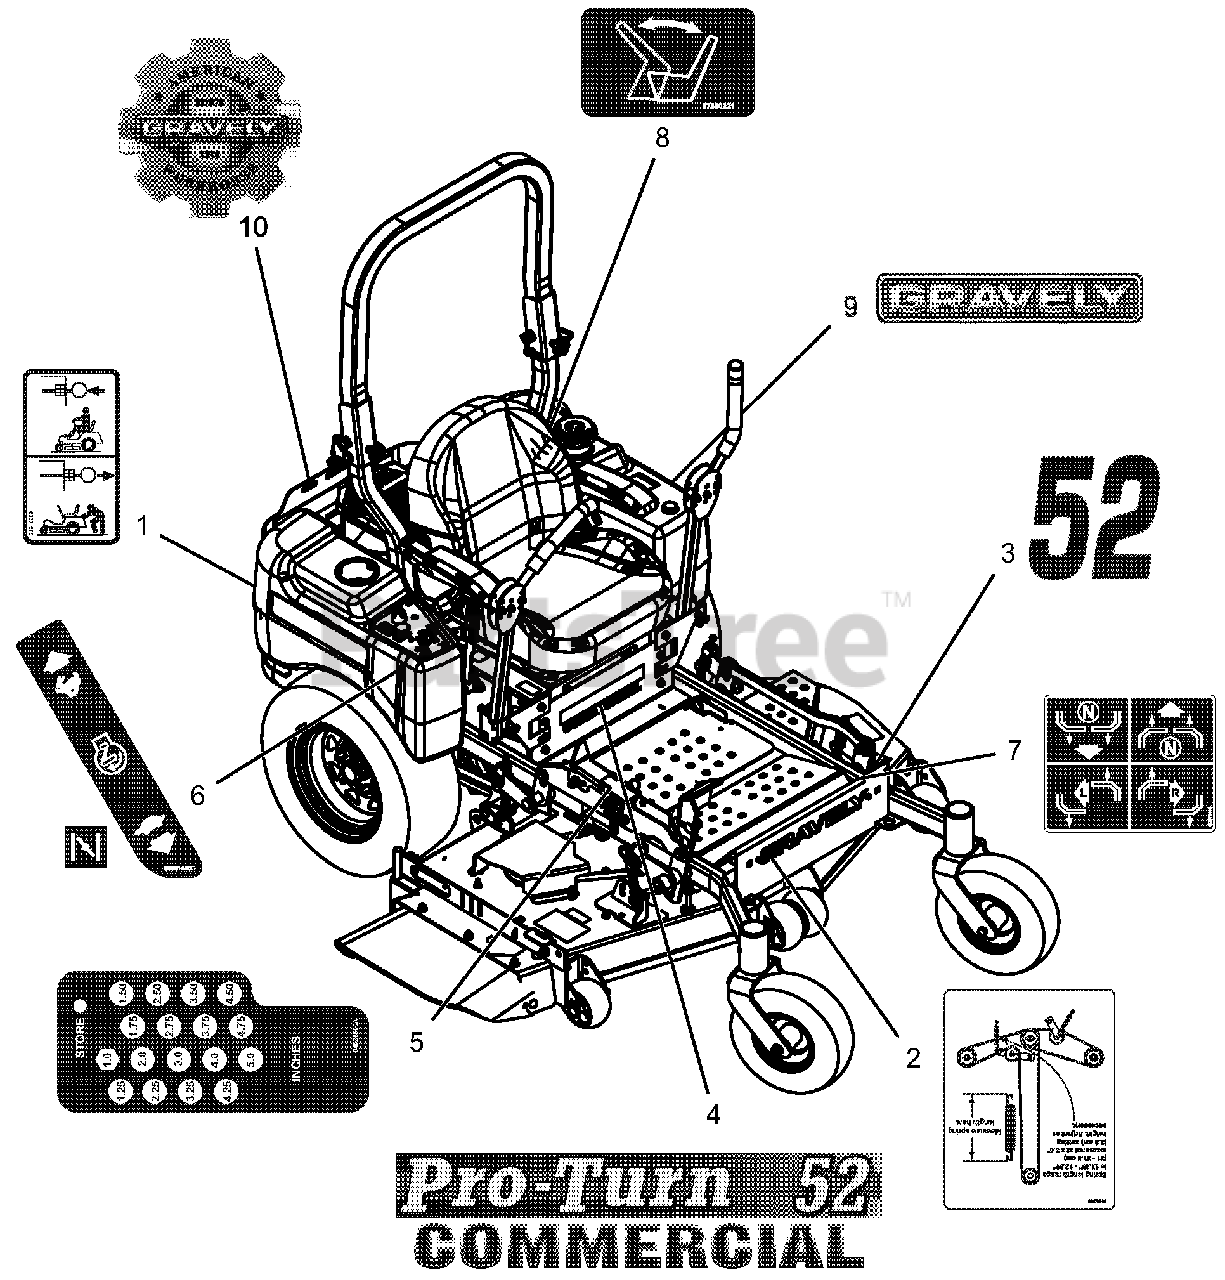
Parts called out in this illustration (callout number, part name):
1	DECAL, TRANSMISSION DISCONNECT
2	DECAL, BELT ROUTING
3	DECAL, 52"
4	DECAL, 52" PRO-TURN
5	DECAL, HEIGHT OF CUT
6	DECAL, SPEED CONTROL
7	DECAL, INSTRUCTIONAL - STEERING
8	DECAL, SEAT RELEASE
9	DECAL, FUEL TANK-GRAVELY
10	DECAL, GRAVELY HERITAGE-LARGE
